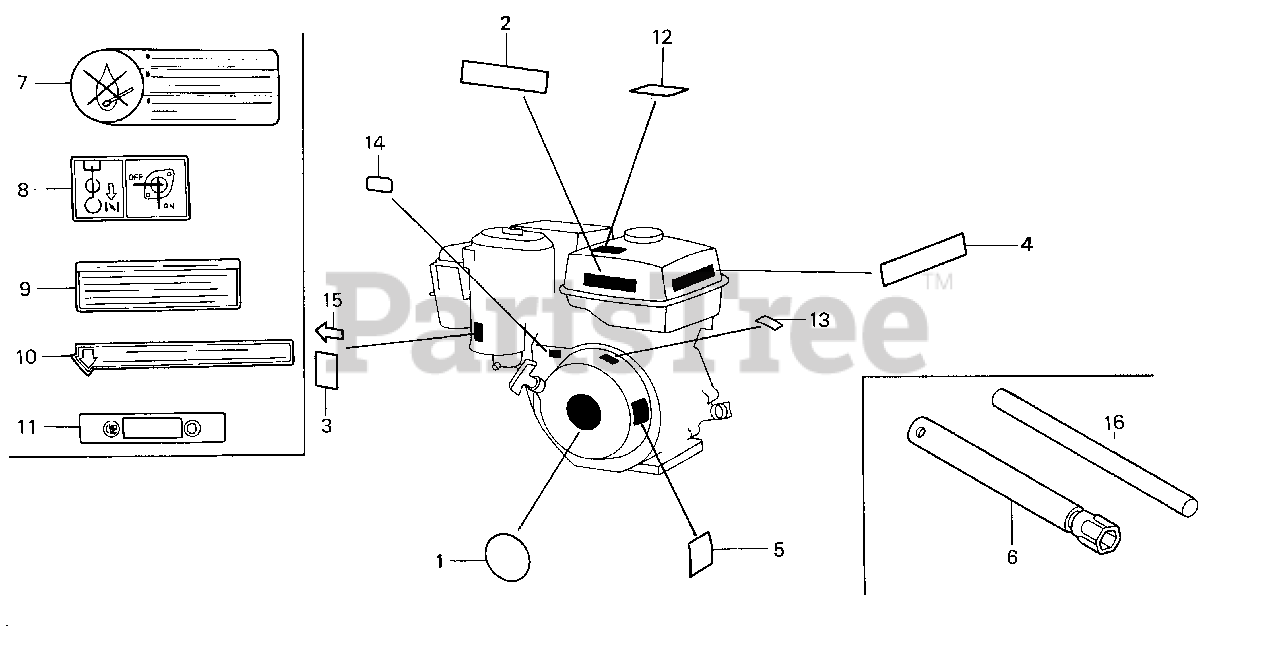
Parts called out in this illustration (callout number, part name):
1	EMBLEM
2	LABEL, CAUTION
3	MARK, CHOKE (EXTERNAL)
4	MARK, OIL ALERT (E)
6	WRENCH, SPARK PLUG
12	MARK, FUEL (EXTERNAL)
